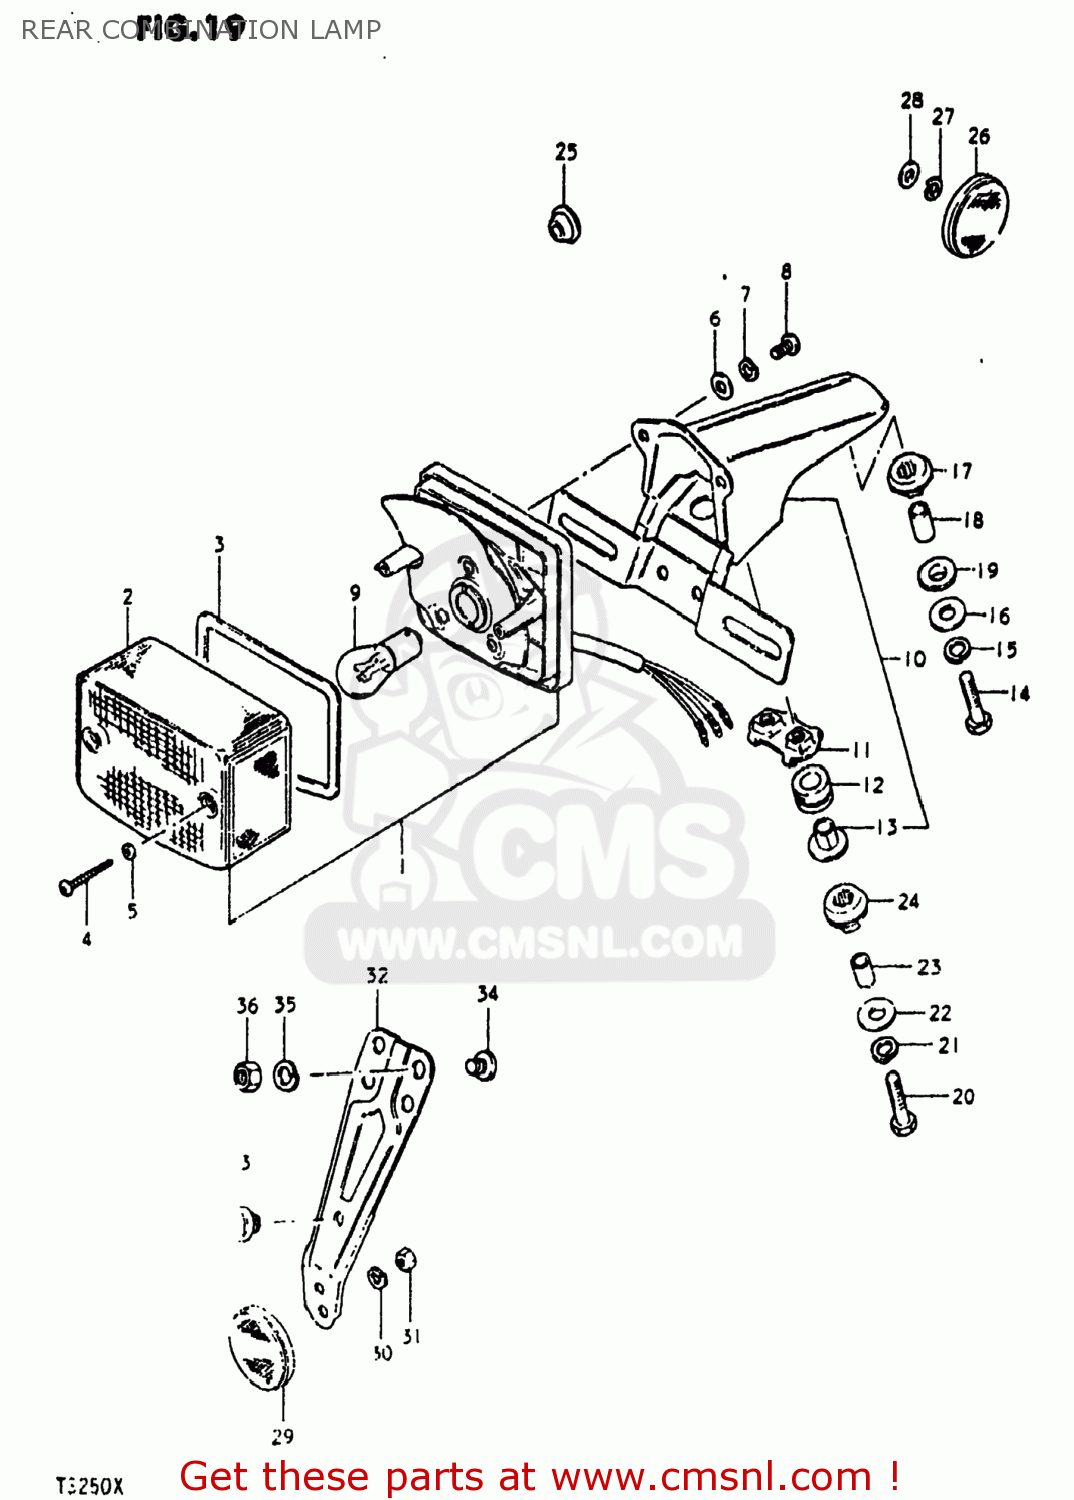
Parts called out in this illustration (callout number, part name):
1	LAMP UNIT,REAR COMBINATION
2	LENS
3	GASKET (NAS)
4	BOLT
5	GASKET (NAS)
6	WASHER
7	LOCK WASHER
8	SCREW
9	BULB(6V32/3CP,STANLEY)
10	BRACKET UNIT,TAIL LAMP
11	PLATE
12	CUSHION
13	SPACER
14	BOLT
15	LOCK WASHER
16	WASHER (6.5X20X1.2)
17	CUSHION
18	SPACER
19	CUSHION
20	BOLT
21	LOCK WASHER
22	WASHER (6.5X20X1.2)
23	SPACER
24	CUSHION
25	GROMMET
26	REFLEX REFLECTOR,FR
27	LOCK WASHER
28	WASHER
29	REFLEX REFLECTOR,RR
30	LOCK WASHER
31	NUT
32	BRACKET
33	CUSHION
34	SCREW
35	LOCK WASHER
36	NUT
